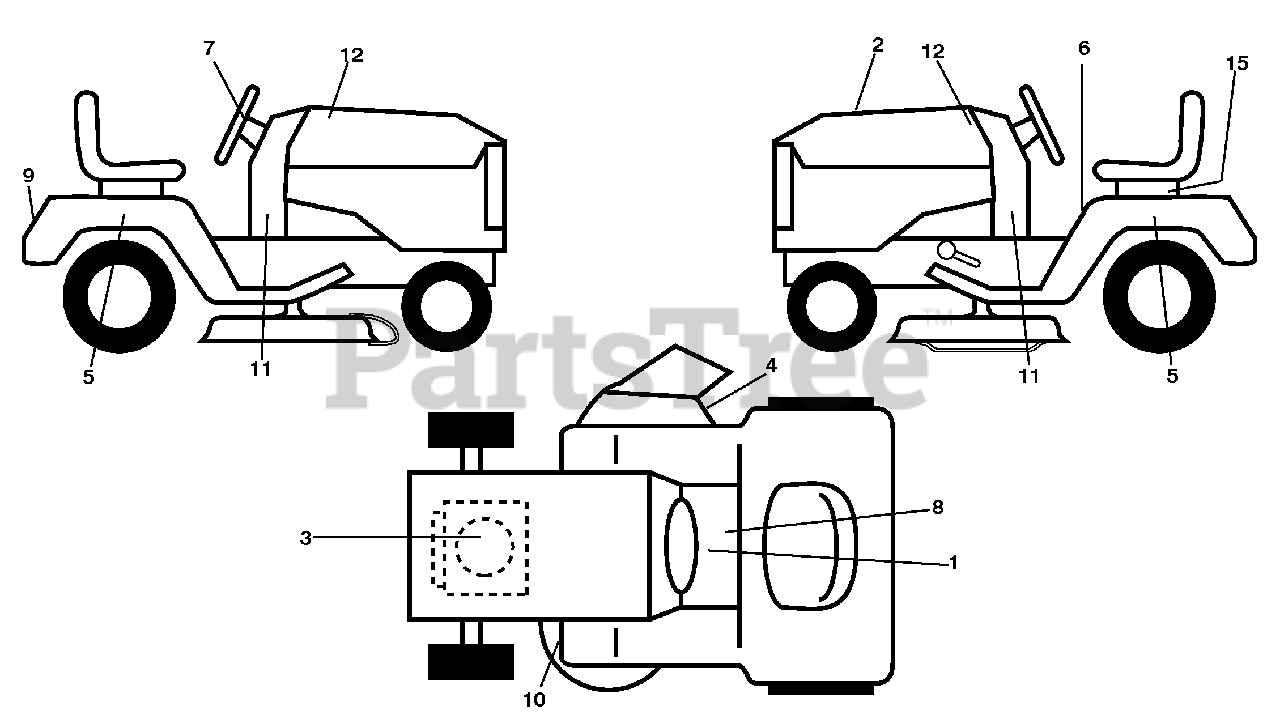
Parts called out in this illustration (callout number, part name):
1	Decal, Dash Warning
2	Decal, Replacement
3	Decal, Engine HP
4	Decal, Warning
5	Decal, Fender
6	Decal, Fender Warning (E&F)
7	Decal, Ins Str Wh
8	Label Emission
9	Decal, Fender
10	Decal, V-Belt Sch.
11	Decal, Lower Dash
12	Decal, Hood RH/LH
15	Decal, Caution, Battery
15	Pad Footrest RH
15	Pad Footrest LH
15	Decal, Handle Lft Height Adj.
15	Manual, Operator's, English & French
15	Manual, Parts, English & French
15	Manual, Operator's, Spanish
